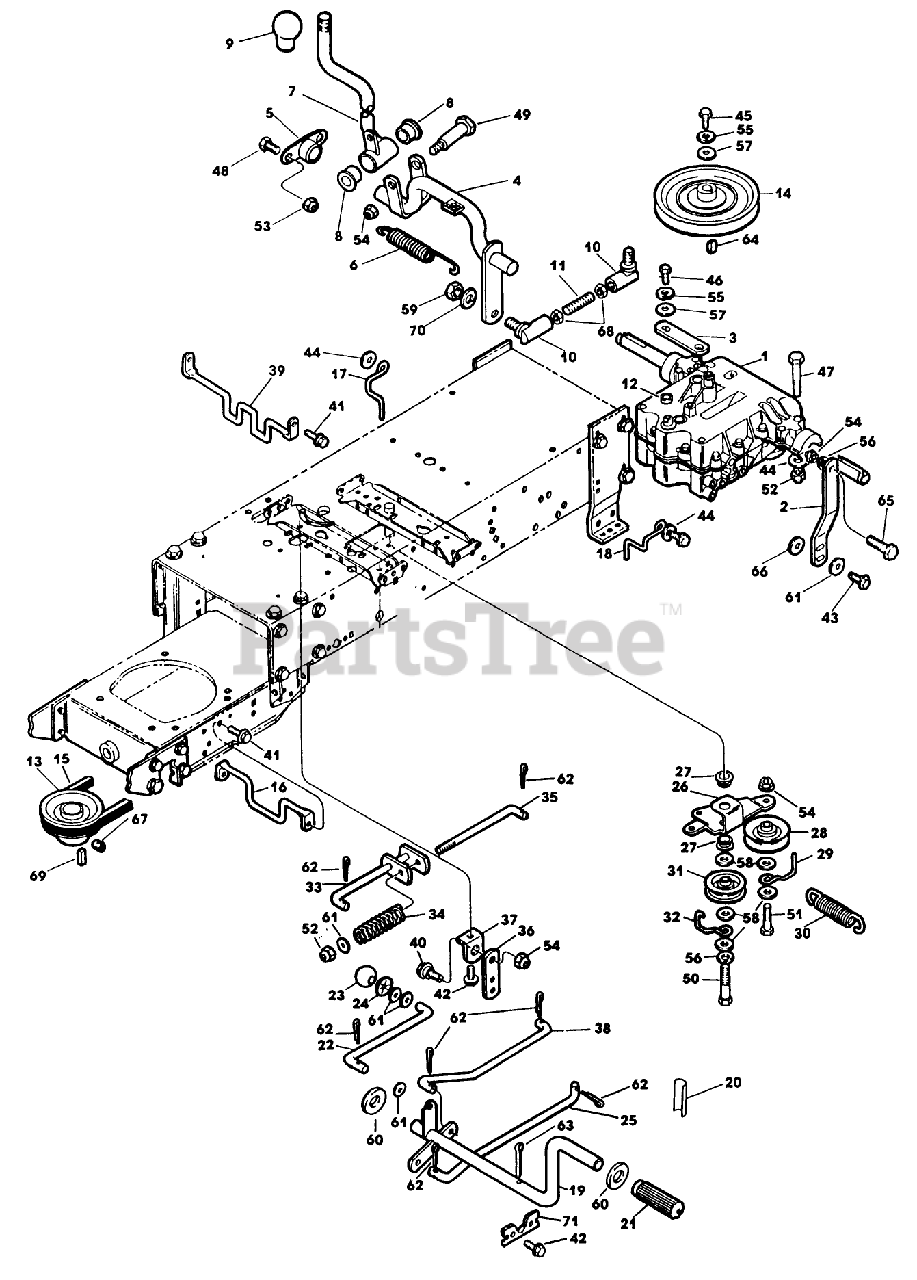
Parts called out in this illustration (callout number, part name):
2	BRACKET - TORQUE
3	LEVER-GEAR SELECT *B
4	CROSS SHAFT AY *B
6	SPRING
8	BUSHING
13	PULLEY
14	PULLEY-TRANSMISSN
15	V-BELT
16	GUIDE
17	FINGER-BELT
18	FINGER-BELT
21	GRIP - FOOT PEDAL
28	PULLEY-IDLER "V"
30	SPRING
32	RETAINER-BELT
36	LINK - BRAKE
46	SCREW-HEXHEAD
48	SCREW-HH
52	NUT
53	NUT-LOCK, CONE
54	NUT-LOCKING
56	WASHER
57	WASHER
58	WASHER
67	SET SCREW
69	KEY
